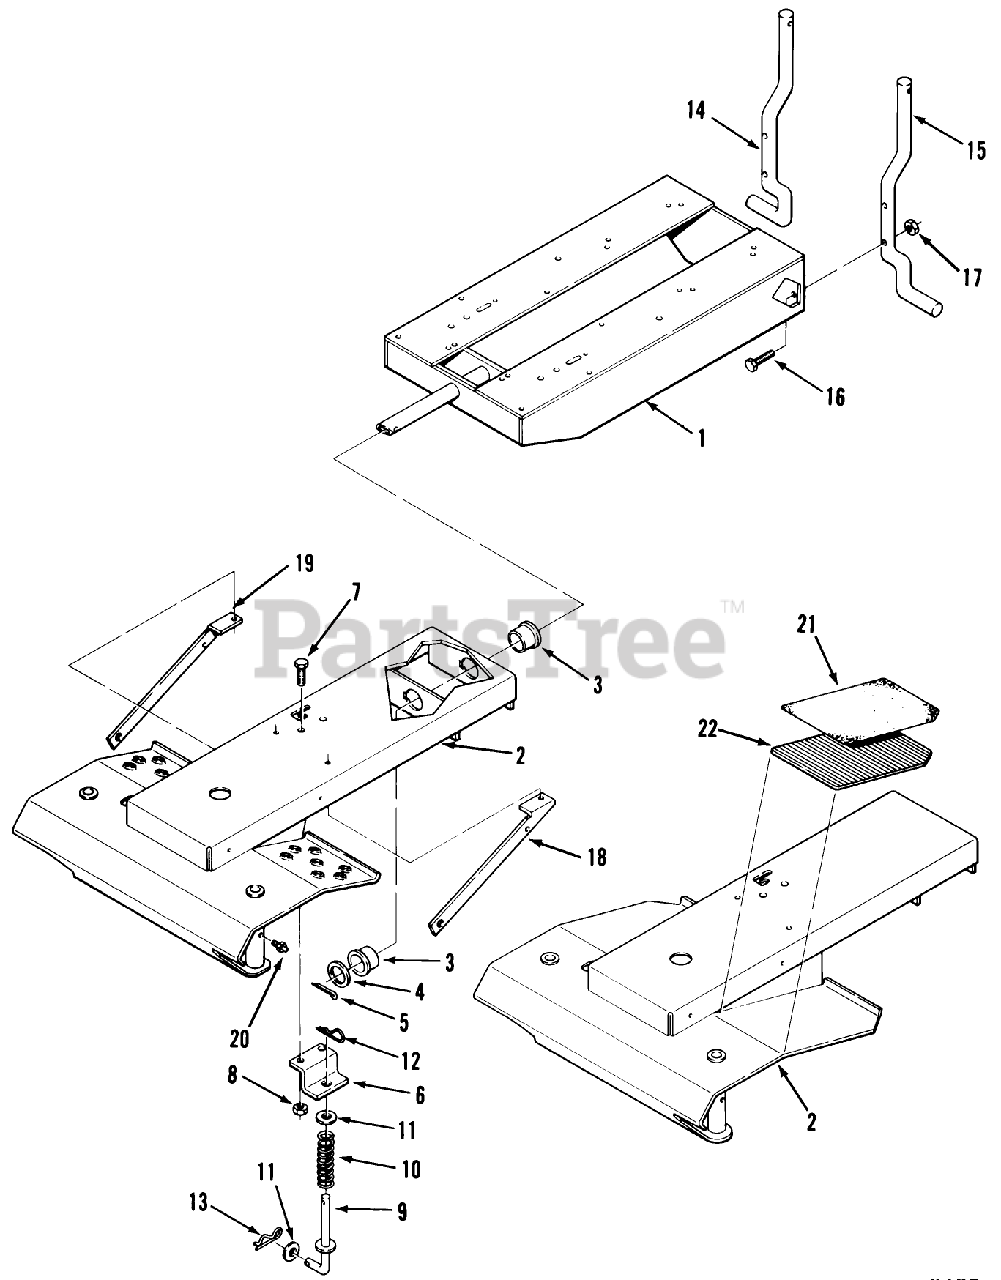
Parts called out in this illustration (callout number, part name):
10	SPRING-COMPRESSION
12	Hairpin Cotter
13	Hairpin
14	REAR ROD RH *B
15	REAR ROD LH *B
22	PAD FOOTREST RH
